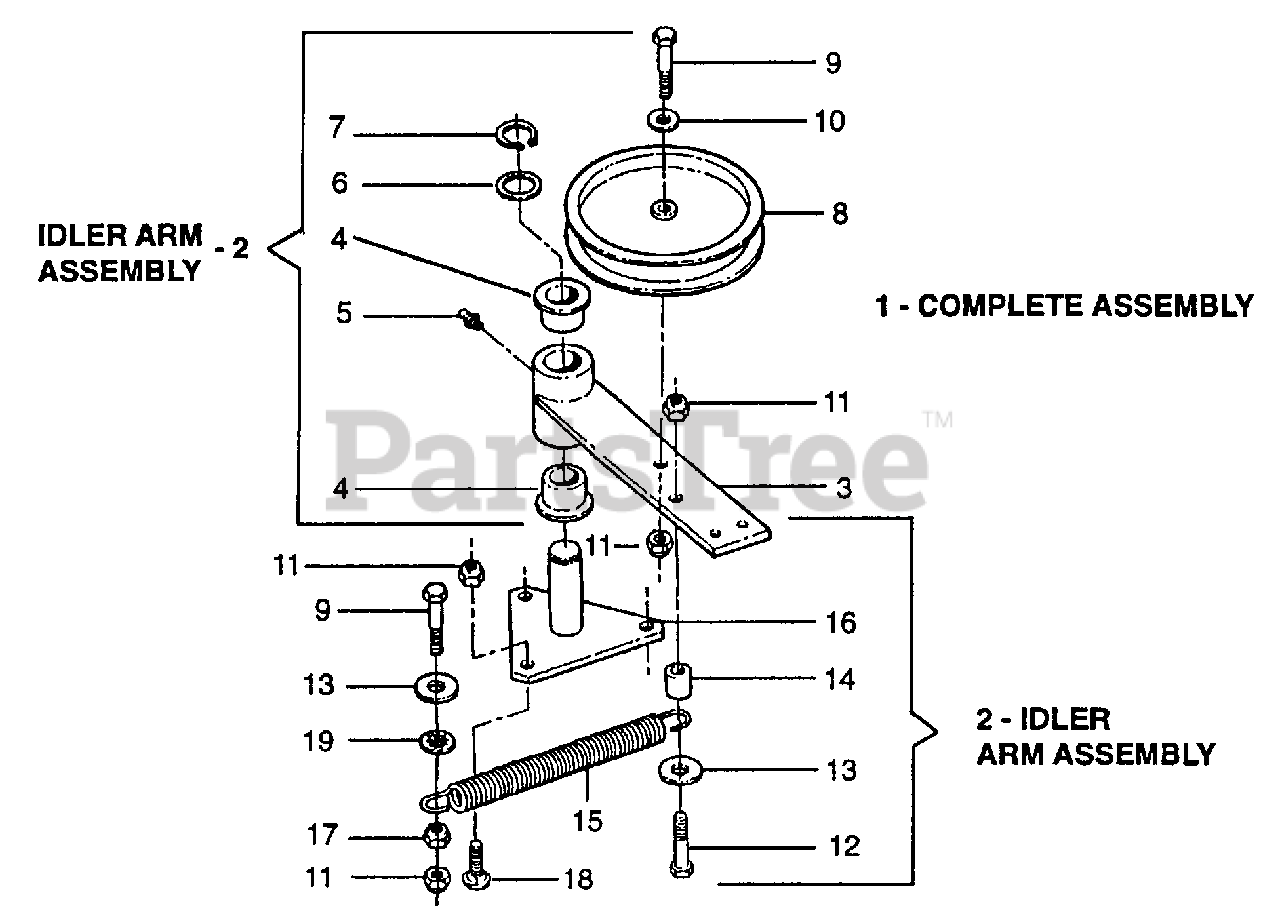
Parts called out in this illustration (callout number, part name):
1	ASSEMBLY, Spring-Loaded Idler Group
2	ASSEMBLY, Idler Arm
3	ARM, Idler (Weldment)
4	BUSHING
5	FITTING, Lube 1/4 - 28 Straight
6	WASHER, 1/32 I.D. x 1-1/4 O.D. Flat
7	E-RING, 1"
8	PULLEY, Idler 5-1/2" O.D.
9	BOLT, 3/8-16 X 2, GD5, CZ
10	WASHER, 3/8" USS
11	NUT, 3/8-16 HEX NYLON LOCK
12	SCREW, 3/8-16 x 1-3/4" Hex Head Cap, Grade 5
13	WASHER, 13/32 x 1-1/2 Yellow Zinc
14	SPACER, 1/2" I.D. x 3/4" O.D.
15	SPRING, Extension
16	PIVOT, Idler (Weldment)
17	NUT, 3/8-16 HEX SERRATED FLANGE
18	BOLT, 3/8-16 x 1" Carriage
19	RETAINER, 3/8" Bolt
